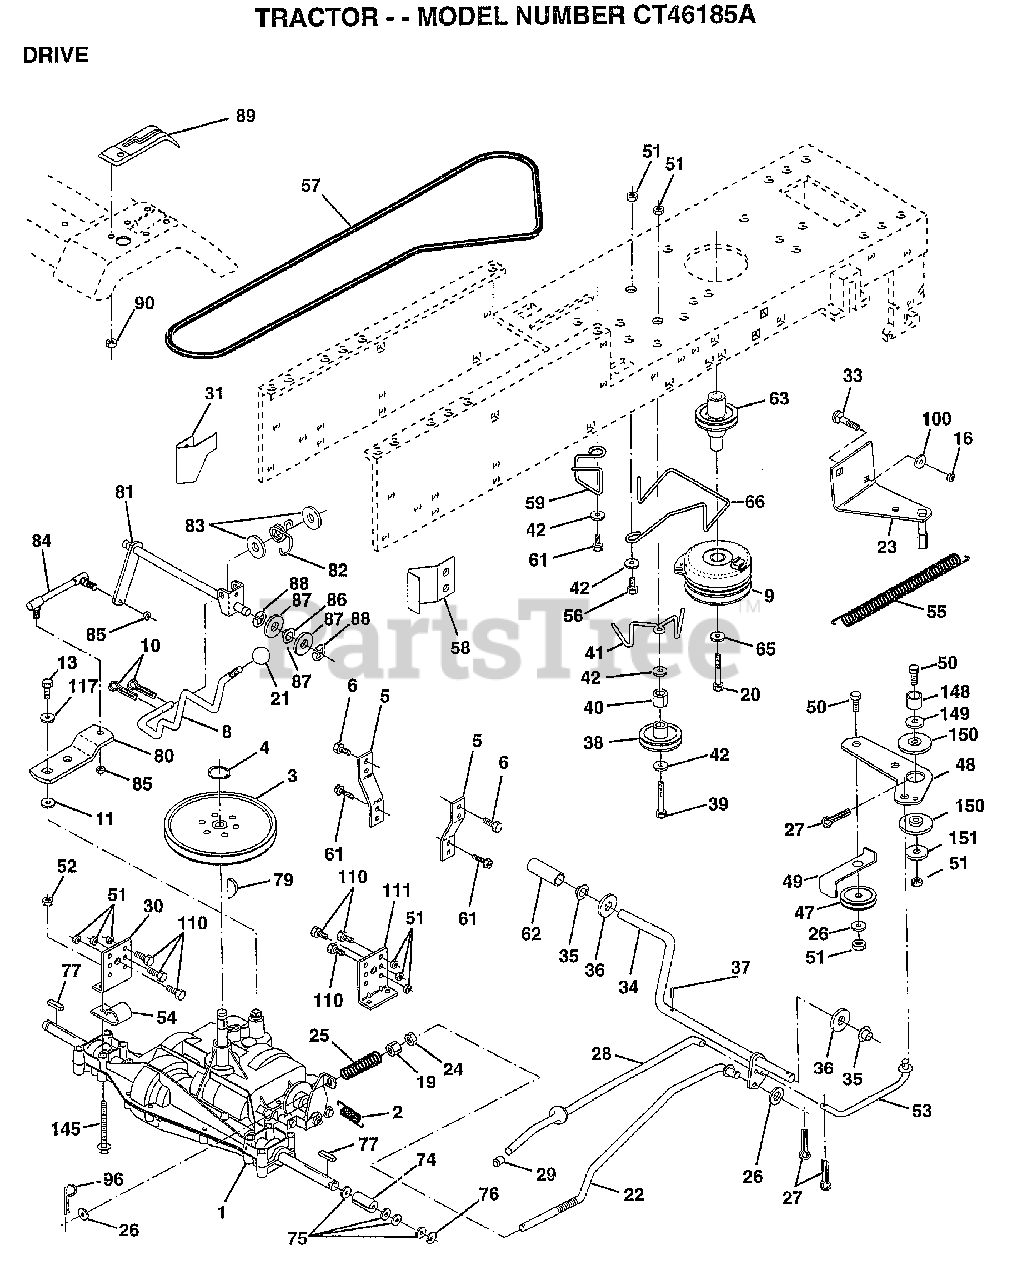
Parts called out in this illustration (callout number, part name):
3	PULLEY TRANSAXLE
4	RING
5	STRAP TORQUE
6	SCREW
8	ROD SHIFT FEND YT
9	CLUTCH.ELECTRIC
10	PIN COTTER 1/8
11	WASH-SHFT PLT LT
13	BOLT.1/4-28.W/PAT
19	NUT
20	BOLT.7/16-20X4.25
21	KNOB T (1/2-HOLE)
22	ROD.ASM.BK.44.MWR
23	BRACKET.CLUT.MTG.
24	NUT
25	"SPRING,ROD BRAKE"
26	WASHER
27	COTTER PIN
28	ROD.BRAKE.PARK.LT
29	PLUNGER CAP T
30	BRKT TRANS LH
31	KEEPER BELT LH
33	BOLT
34	SHAFT ASM-PEDAL F
35	NYLON BEARING
36	WASHER LT
38	PULLEY.IDLER.FLAT
39	BOLT
40	SPACER T
42	WASHER
48	BELLCRANK.CLUTCH
49	RETAIN BELT
53	"LINK, CLUTCH T"
54	"CLIP,INSULATOR"
55	"SPRING, RETURN LT"
57	V-BELT.DRIVE
58	"KEEPER,BELT RH"
59	KEEPER BELT CNTSP
61	SCREW
62	PEDAL COVER T
63	PULLEY.CLUTCH.EVX
65	LOCKWASHER
66	KEEPER-BELT
74	SPACER HYT
75	WASHER
76	E RING HYT
77	SQ KEY STD
80	"ARM,SHIFT"
81	SHAFT ASM CROSS
82	"SPRING,TORSION"
83	WASHER
84	"ROD LINK,SHIFT AD"
85	NUT.CNT.LOCK.1/4
86	BUSHING
87	WASHER D
88	KLIP RING
89	CONSOLE SHIFTER
90	NUT
100	WASHER M
111	BRKT TRANS RH
117	WASHER PM
145	BOLT.HEX.FLGHD
149	SPACER RETAINER
150	BUSHING.NYLON
151	WASHER
